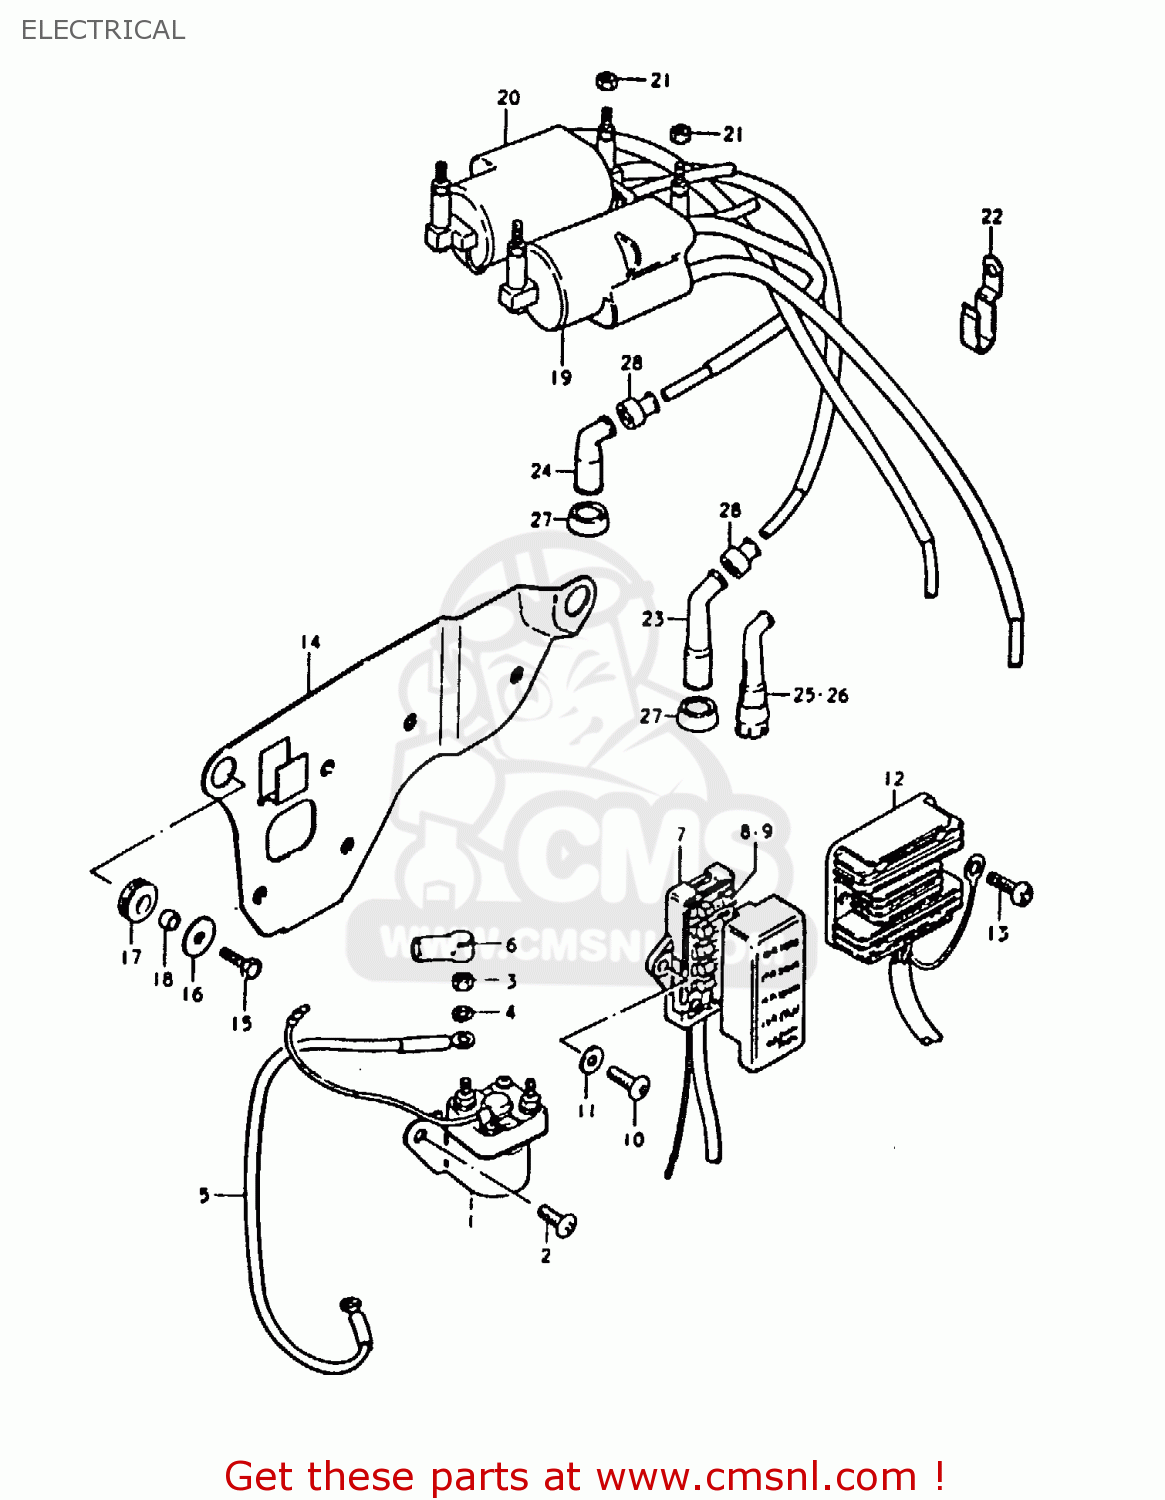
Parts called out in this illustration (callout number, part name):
1	RELAY ASSY,STARTING MOTOR
2	SCREW
3	NUT 6MM
4	LOCK WASHER
5	WIRE,STARTER MOTOR LEAD
6	CAP,STARTER RELAY
7	BOX ASSEMBLY,FUSE
8	FUSE(10A)
9	FUSE(15A)
10	SCREW
11	WASHER
12	RECTIFIER ASSEMBLY
13	SCREW 6X12
14	PLATE,ELECTRIC PARTS HOLDER
15	BOLT, UPPER
16	WASHER(6,5X22X1.6)
17	CUSHION
18	SPACER (7X9X7)
19	COIL ASSEMBLY,IGNITION
20	COIL ASSEMBLY,IGNITION
21	NUT
22	CLAMP
25	CAP,SPARK PLUG
26	CAP, SPARK PLUG (S)
28	SEAL,SPARK PLU
